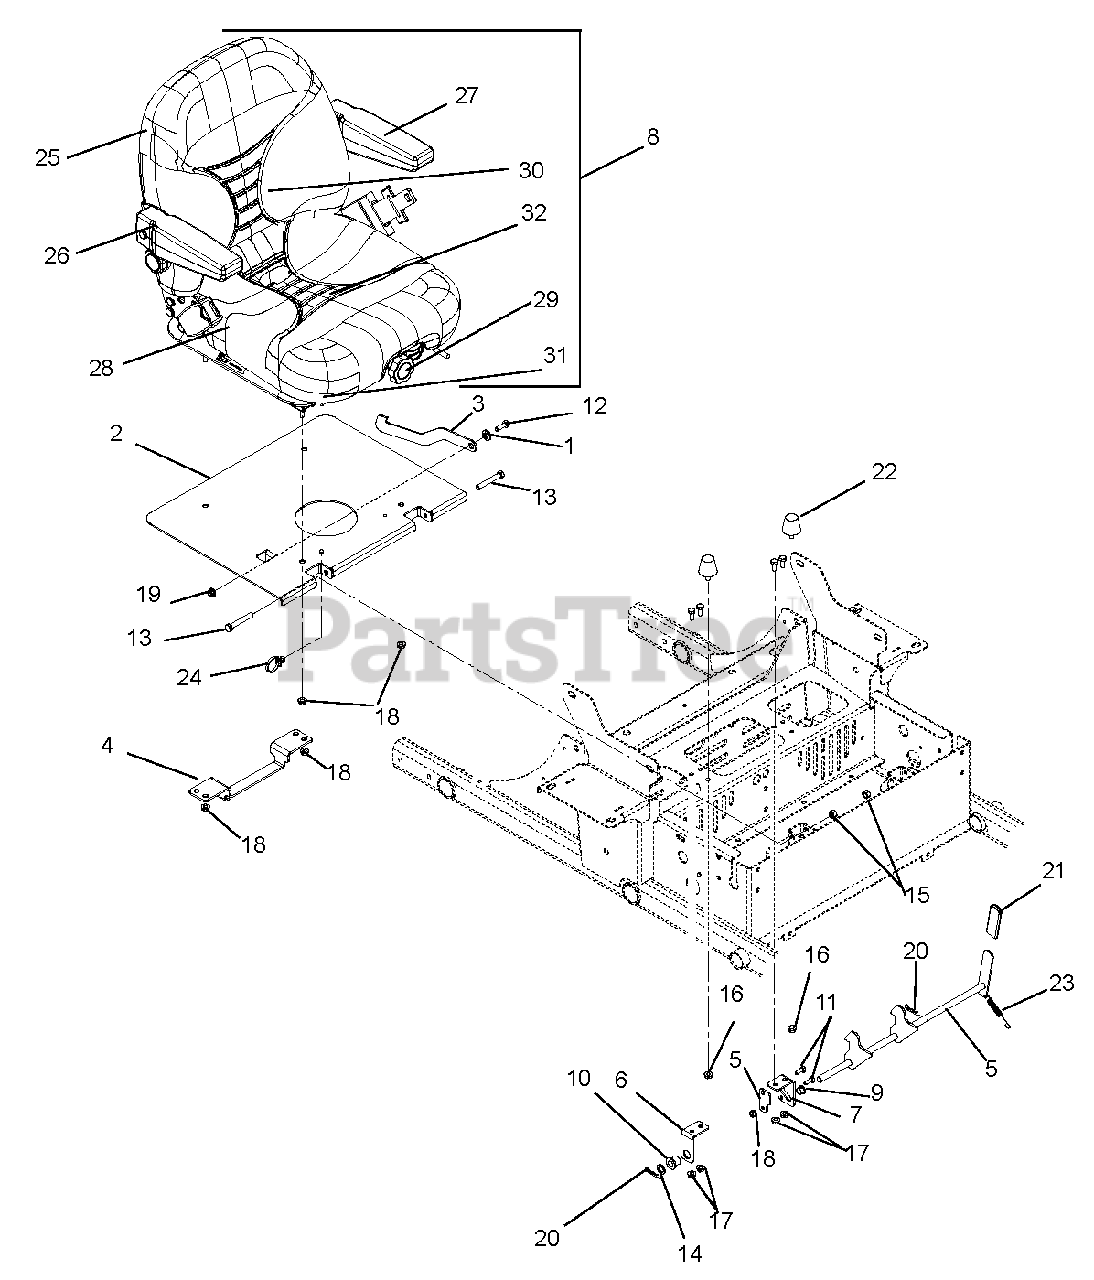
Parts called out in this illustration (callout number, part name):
1	Bushing, Flange .325 x .499 x .26 x .88
2	Seat Plate Weldment – Black
3	Stop, Seat Pivot
4	Bracket, Seat Latch
5	Weldment, Seat Latch
6	Mount, Seat Latch – Right Hand
7	Mount, Seat Latch – Left Hand
8	Seat, SUSP, with Seat Belt, Light Gray
9	Bushing, Polyliner – .50 Split
10	Bushing, Flange .515 x .750 x .745 x 1.00NY
11	Bolt, Hex .25-20 x .75 Grade 5 YWZC
12	Bolt, Hex .31-18 x .75 Grade 5 YWZC
13	Bolt, Hex .38-16 x 2.50 Grade 5 YWZC
14	Washer, Flat Steel .52 x .827 x .062 YWZC
15	Nut, Locking Center .38-16 YWZC
16	Nut, Spin Lock Flange .312-18 YWZC
17	Nut, Locking Top Flange .31-18 YWZC
18	Nut, Locking Top Flange .25-20 YWZC
19	Nut, Locking Nyloc Flange .31-18 YWZC
20	Pin, Hair Internal .08 x .38 x 1.42 YWZC
22	Bumper, Rubber Cone, Stud Mount
23	Spring, Tension .043 x .44 x 3.31 WLD 5.8
24	Cable Tie with Tree (.25 Hole)
25	Kit, Back Cushion, Light Gray
26	Kit, Armrest Assembly – Right Side
27	Kit, Armrest Assembly – Left Side
28	Kit, Seat Cushion, Light Gray
29	Kit, Seat Knobs
30	Kit, Seat Back
31	Kit, Seat Slides
32	Kit, Seat, Spring and Saddle
